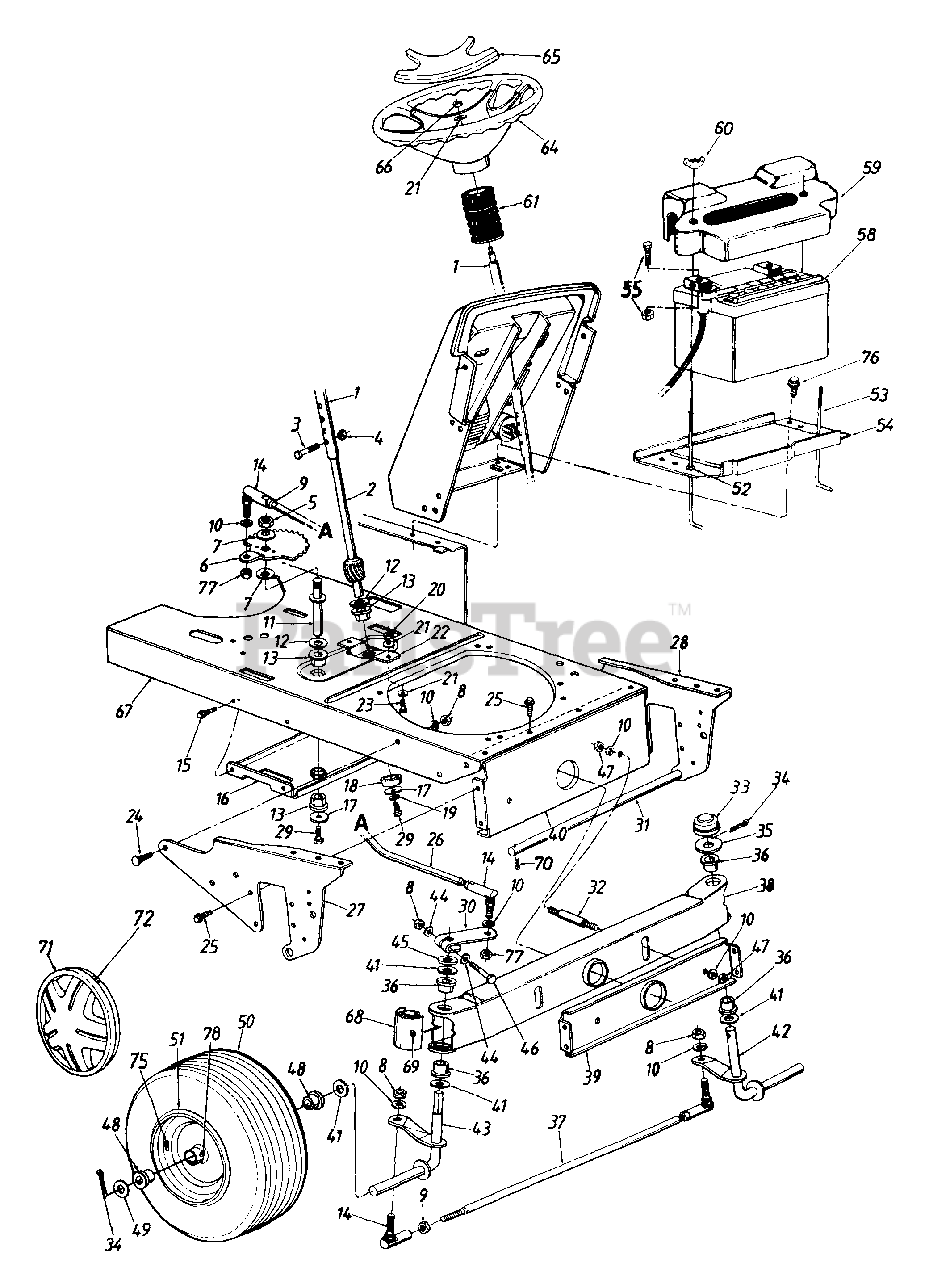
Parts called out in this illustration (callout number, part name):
1	Steering Column Ass'y.
2	Lower Steering Shaft
3	Hex Bolt 1/4-20 x 1.31" Lg.
4	Hex L-Nut 1/4-20 Thd.
5	Hex Nut 5/8-18 Thd.
6	Steering Gear Segment
7	Bell-Wash. 5/8" I.D. x 1.25" O.D.
8	Hex Nut 3/8-24 Thd.
9	Hex Jam Nut 3/8-24 Thd.
10	L-Wash. 3/8" I.D.
11	Steering Gear Segment Shaft
12	Fl-Wash. .64" I.D. x 1.24" O.D.
13	Hex Flange Brg. .63" I.D.
14	Ball Joint Ass'y.
15	Hex Wash. Hd. TT-Tap Scr. 1/4-20 x .5" Lg.
16	Deck Idler Support Brkt.
17	Fl-Wash. .33" I.D. x 1.25" O.D.
18	Spacer .985" I.D. x 1.25" O.D.
19	L-Wash. 5/16" I.D.
20	Hex Nut 5/16-24 Thd.
21	Bell-Wash. .345" I.D. x .88" O.D.
24	Ribbed Neck Bolt 3/8-24 x .8" Lg.
25	Hex Wash. TT-Tap Scr. 5/16-18 x .62" Lg.
26	Steering Drag Link
27	Pivot Bar Side Plate - R.H.
28	Pivot Bar Side Plate - L.H.
29	Hex Bolt 5/16-18 x .62" Lg.
30	Steering Arm
31	Deck Connecting Rod
32	Pivot Bar Shld. Bolt 3/8-16 x 5/8" Lg.
33	Cap
34	Cotter Pin 5/32" Dia.
36	Flange Brg. .757" I.D.
37	Tie Rod 20.25" Lg.
38	Pivot Bar Assy.
41	Fl-Wash. .76" I.D. x 1.49" O.D.
42	Front Axle Ass'y. - L.H.
43	Front Axle Ass'y. - R.H.
44	Bowed Washer
45	Spacer .755" I.D. x 1.25" O.D.
46	Hex Bolt 3/8-24 x 2.25" Lg.
47	Hex Nut 3/8-16 Thd.
48	Ball Brg. .75" I.D.
49	Fl-Wash. .71" I.D. x 1.5" O.D.
51	Rim Only
52	Push Nut
53	Battery Hold Down Rod
54	Battery Plate
55	Comes w/Battery
58	Battery
59	Battery Cover
60	Wing Nut Plastic 1/4-20 Thd.
61	Steering Bellow
64	Steering Wheel
65	Steering Wheel Cap
66	Hex L-Nut 5/16-24 Thd.
69	Grease Fitting
70	Internal Cotter Pin
71	Hub Cap
72	Spring Clip
75	Air Valve
76	Hex AB-Tap Scr. 1/4 x .62" Lg.
77	Hex Jam L-Nut 3/8-24 Thd.
78	Grease Fitting
